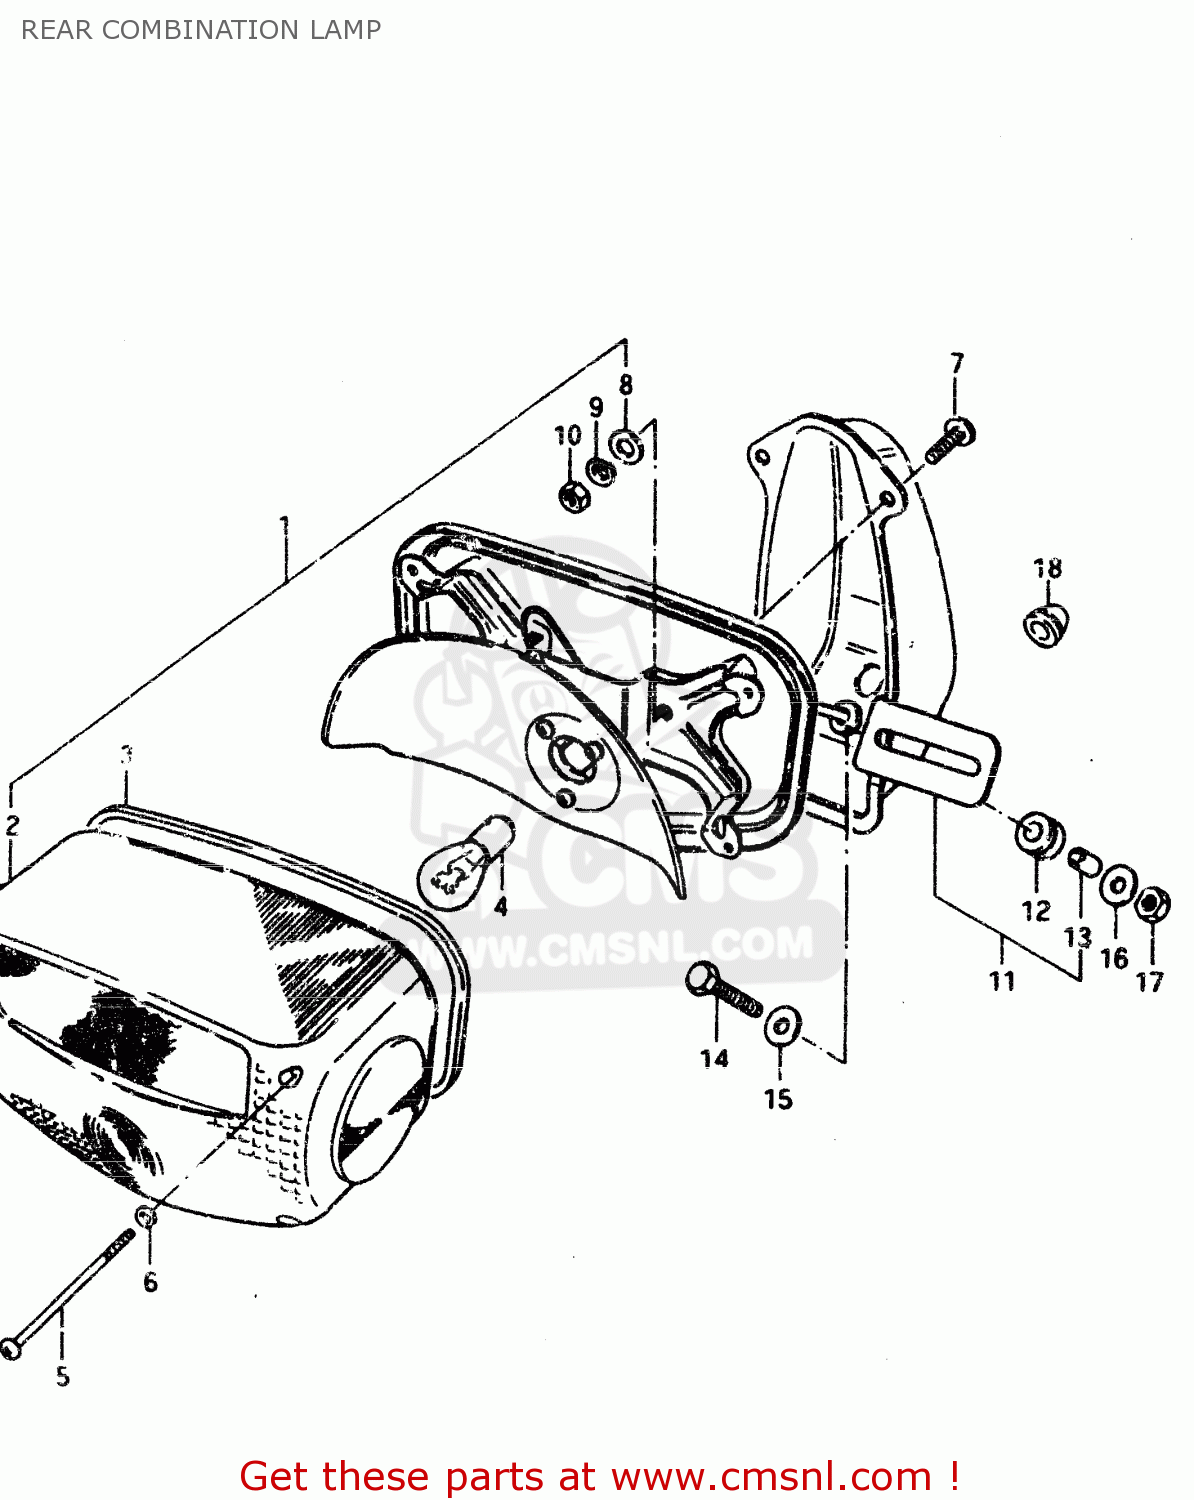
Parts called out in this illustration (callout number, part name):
1	LAMP UNIT, TAIL
2	LENS
3	GASKET (NAS)
4	BULB(12V21/5W)
5	SCREW (4X55)
6	GASKET (NAS)
7	SCREW 6X12
8	WASHER
9	LOCK WASHER
10	NUT
11	BRACKET ASSY
12	CUSHION
13	SPACER
14	BOLT
15	WASHER (6.5X20X1.2)
16	WASHER
17	NUT
18	GROMMET
